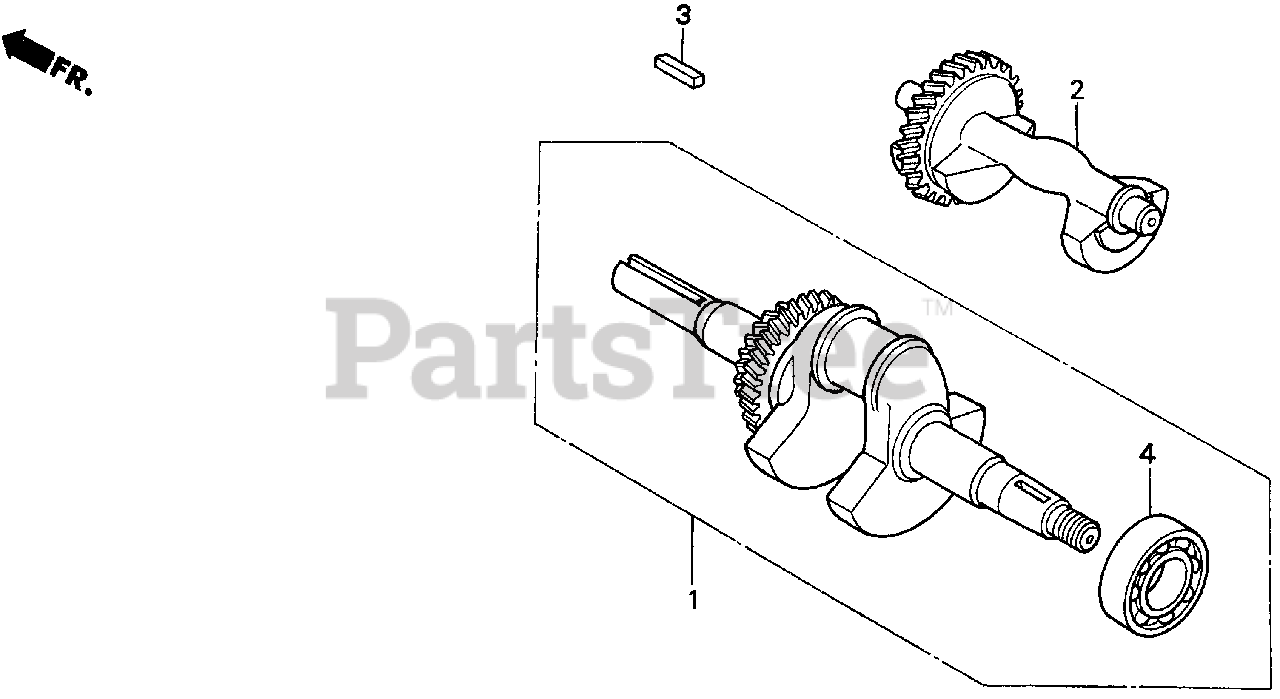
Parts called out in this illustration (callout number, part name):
1	CRANKSHAFT
2	WEIGHT, BALANCER
3	KEY (7X7X33) (YELLOW)
4	BEARING, RADIAL BALL (6207S)
